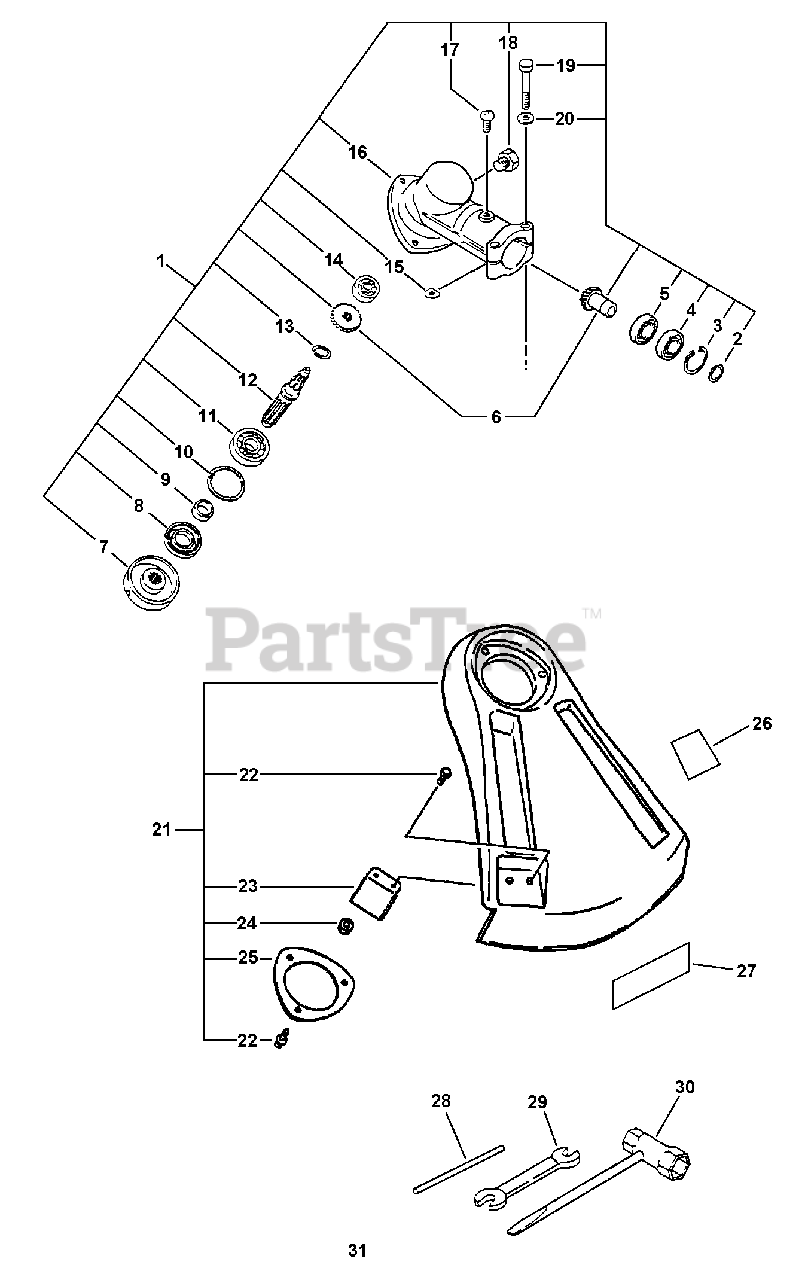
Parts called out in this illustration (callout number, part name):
1	GEAR CASE ASSY
2	RING, SNAP Ø10
3	RING, SNAP Ø22
4	BEARING, BALL 6900Z
5	BEARING, BALL 6900
6	GEAR SET
7	PLATE, ADAPTOR - UPPER
8	SEAL, OIL 22
9	SPACER 11.8×15×9
10	RING, SNAP Ø32
11	BEARING, BALL 6201
12	SHAFT, GEAR
13	RING, SNAP Ø12
14	BEARING, BALL 609
16	HOUSING, GEAR CASE
17	SCREW 5×10
18	BOLT 8×8 SP
19	BOLT 5×35 SP
20	WASHER, FLAT 5.5×10×0.8
21	DEBRIS SHIELD KIT
22	SCREW 5×16
23	CUTTER, LINE
24	NUT M5
25	BRACKET, SHIELD
26	LABEL, CAUTION
27	LABEL, ECHO
28	TOOL, LOCKING 5×120 MM
29	SPANNER 8×10
30	T-WRENCH
